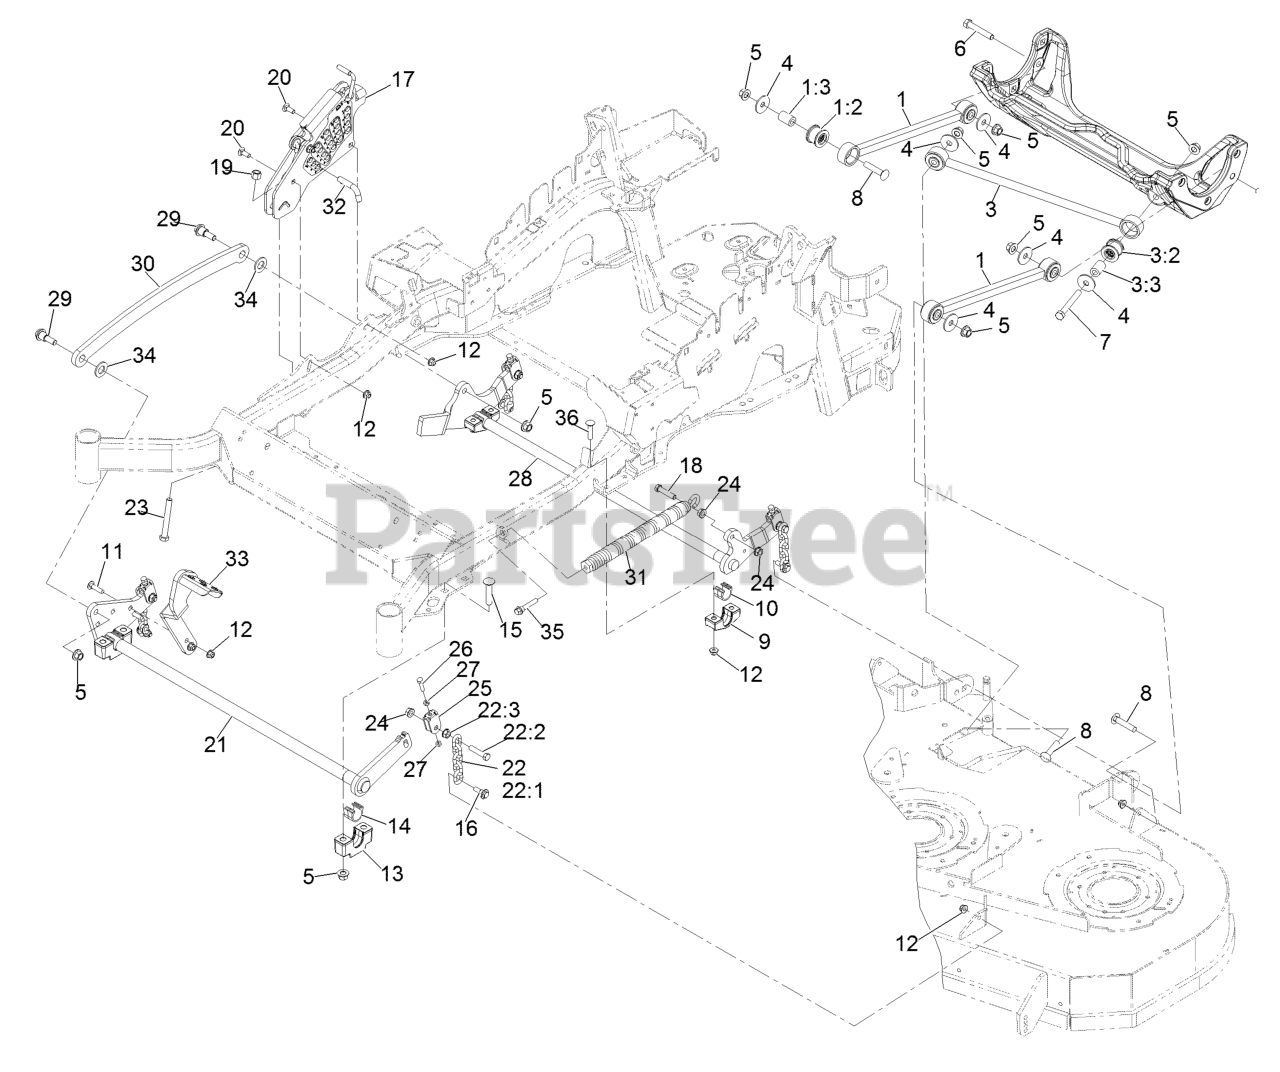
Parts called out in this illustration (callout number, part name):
1	Long Strut ASM
1:2	Bushing-Suspension, Rubber
3	Panhard Rod ASM
3:2	Bushing-Suspension, Rubber
5	Nut-Lock 1/2-13
6	Screw-HH 1/2-13 X 3
7	Screw-HH 1/2-13 X 4
8	Bolt-Carriage 1/2-13 X 2 1/2
9	Support-Cross Shaft, Bearing Rear
10	Bearing-Cross Shaft, Rear
11	Bolt-Carriage 3/8-16 X 1 1/2
12	Nut-Nyloc 3/8-16 Flg
13	Support-Cross Shaft, Bearing
14	Bearing-Cross Shaft, Front
15	Bolt-Carriage 1/2-13 X 2 1/2 Spl Neck
16	Screw-Hex Flange 3/8-16 X .80
17	HOC ASM
18	Screw-HH 7/16-14 X 2
19	Nut-Nyloc 1/2-13
20	Bolt-Carriage 3/8-16 X 1
21	Decklift-Front
22	Deck Lift Chain ASM
22:1	Chain-Lift, Deck
22:2	Screw-HH 7/16-14 X 2
22:3	Nut-Whizlock 7/16-14
23	Bolt-HH 1/2-13 X 4 Tap
24	Nut-Whizlock 7/16-14
25	Yoke-Adjust, Deck
26	Screw-HH 5/16-18 X 1 1/4
27	Nut-Jam 5/16-18
28	Lift-Deck, Rear
29	Screw-Shoulder HHF 1/2-13 X 1.12
30	Link-Lift, Deck
31	Spring-Extension
32	Pin-HOC
33	Lever-Foot
34	Washer-3/4 SAE
35	Screw-Shcs 3/8-16 X 2.212
36	Bolt-Carriage 3/8-16 X 2 1/4
